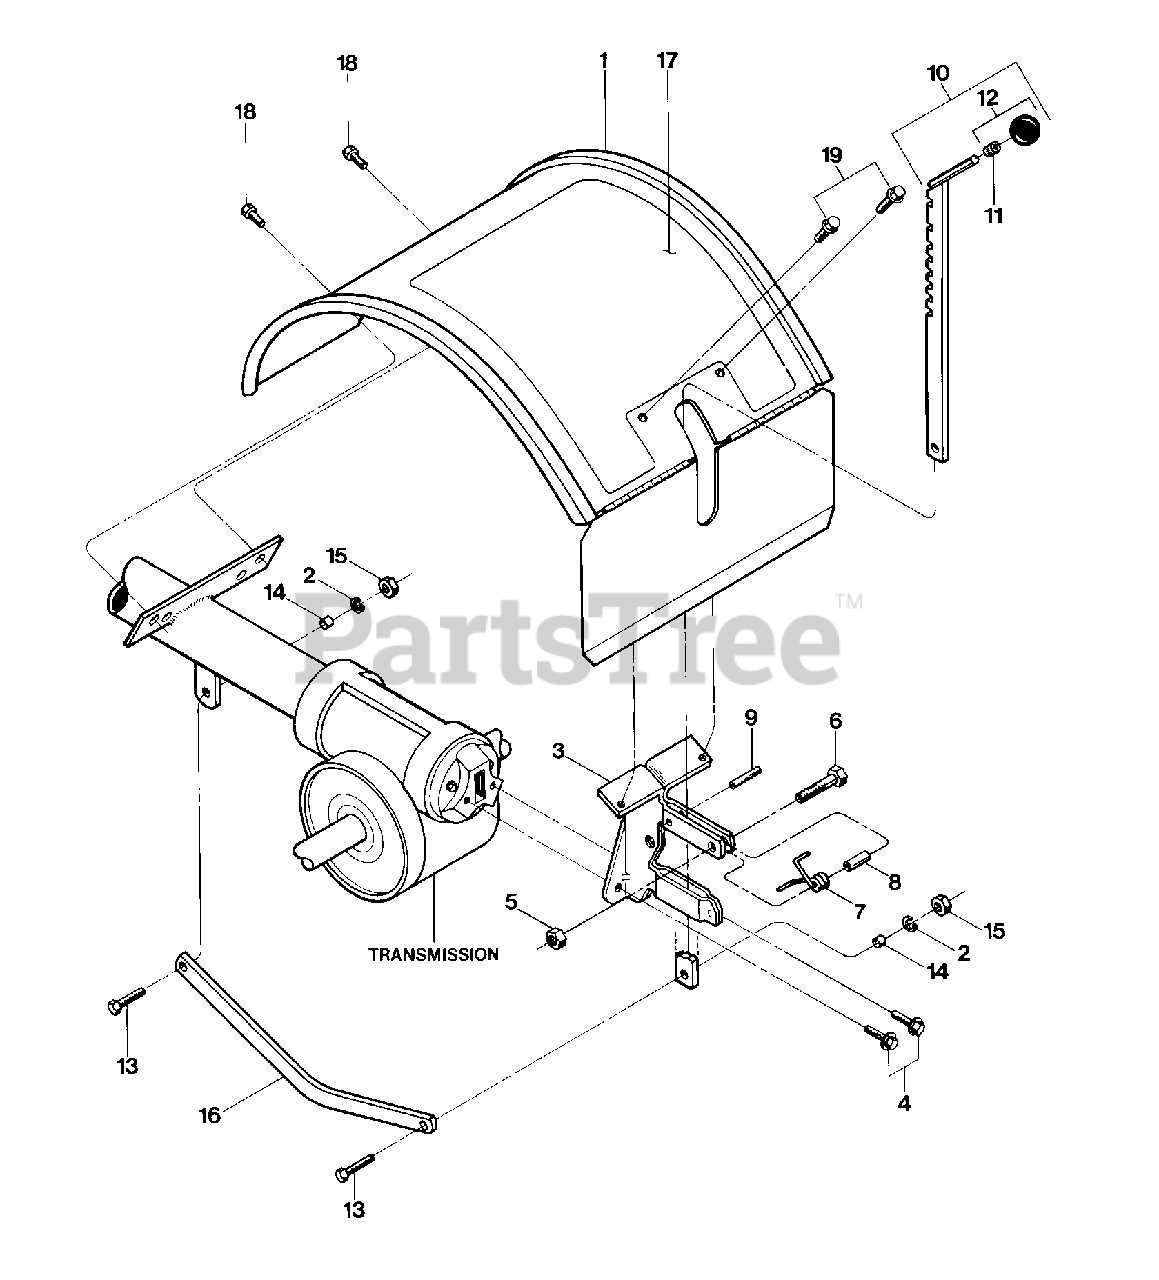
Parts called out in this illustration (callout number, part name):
1	Hood-tine cover, with hinged flap
2	Lockwasher-3/8
3	Bracket-hood & depth regulator
4	Screw-flanged hex hd., 5/16-18 x 5/8
5	Locknut-hex, 1/4-20
6	Screw-hex hd., 1/4-20 x 1
7	Spring-depth regulator plunger
9	Roll Pin-1/4 x 1 (spiral)
10	Bar Assembly-depth adjustment
11	Ring-retaining, tolerance ring
12	Knob-depth regulator
13	Screw-hex hd, 3/8-16 x 1-1/4
14	Bushing-spacer, drag bar
15	Nut-hex, 3/8-16
16	Drag Bar-depth regulator
17	Decal-tiller operating instructions
18	Screw-hex hd, self-tapping, 5/16-18 x 1/2
19	Screw-flanged hex hd, self-tapping, 1/4-20 x 1/2
